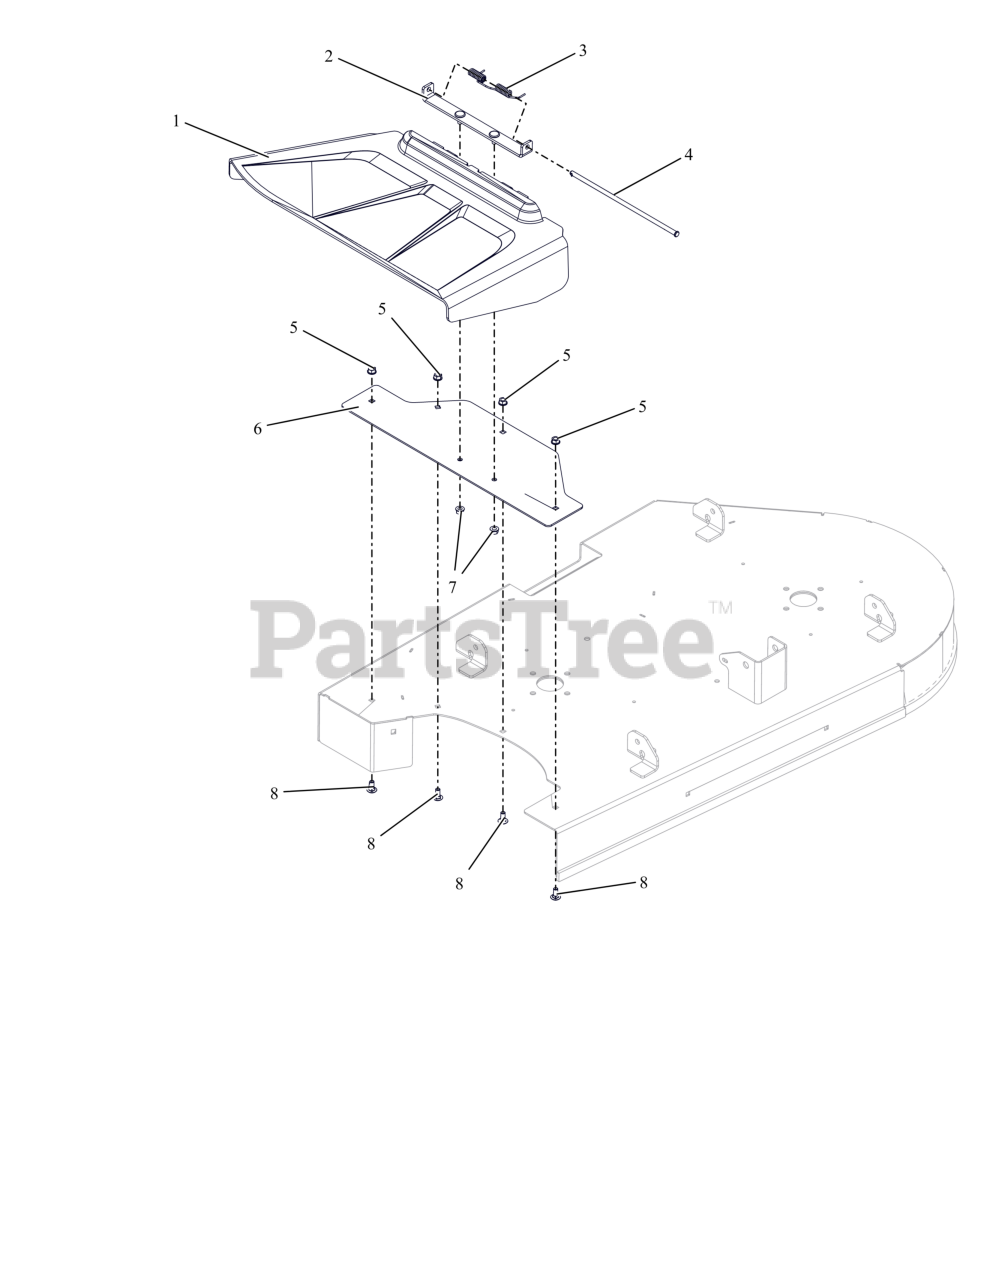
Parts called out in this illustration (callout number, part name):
1	CHUTE, SIDE DISCHARGE
3	SPRING-TORSION
4	PIN, SLIC-.312X10.45
5	NUT,LK-CTR-FLG .31-18 GF ZCC
6	PLATE, DECK - DISCHARGE (ORANGE)
7	NUT,LK-CTR-FLG .31-18 GF ZCC
8	BLT,RHSN .31-18X.75 G5 ZCC
